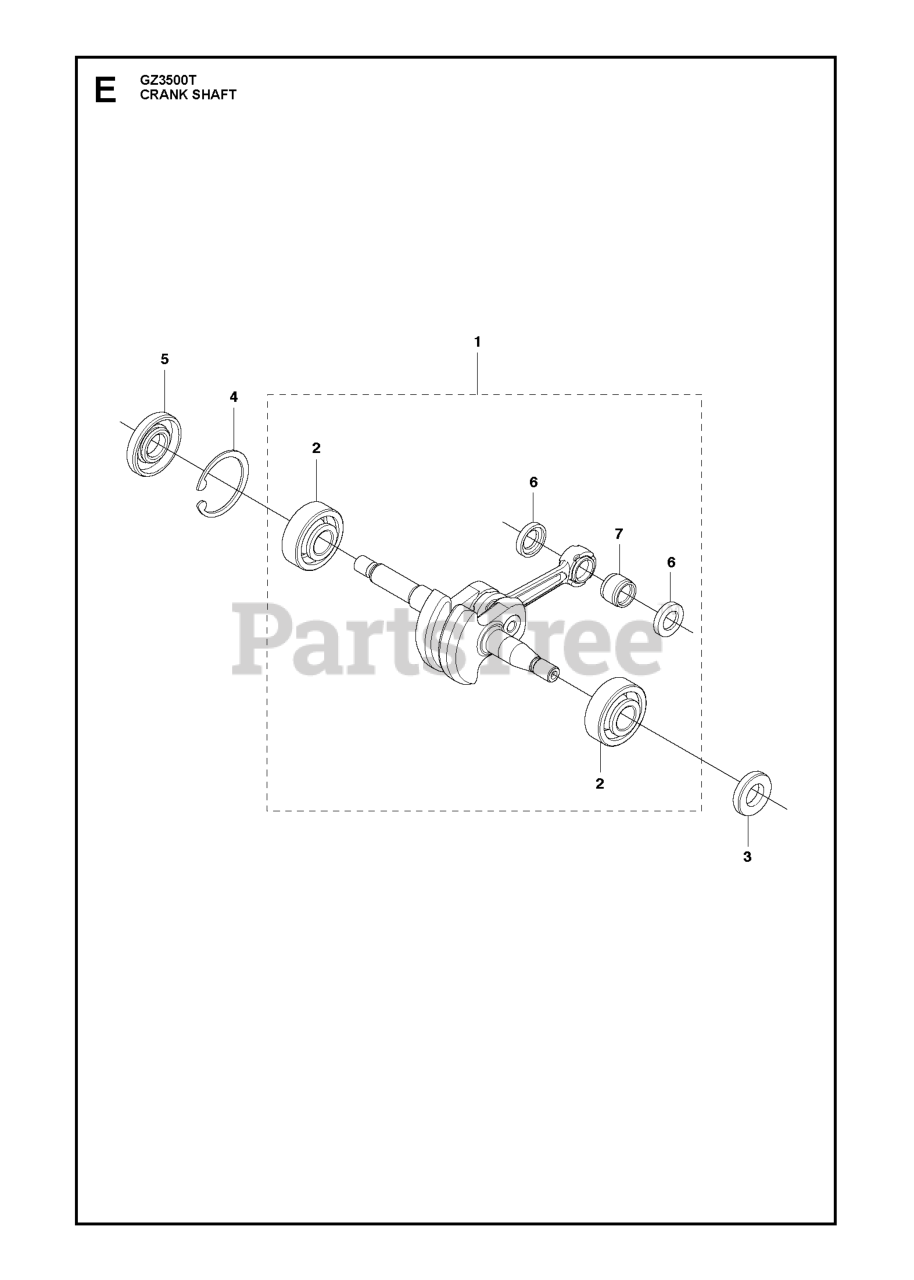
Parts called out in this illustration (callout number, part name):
1	CRANKSHAFT
2	BEARING
3	OIL SEAL(RPLS 284121210)
6	WASHER
7	ROLLER BEARING
